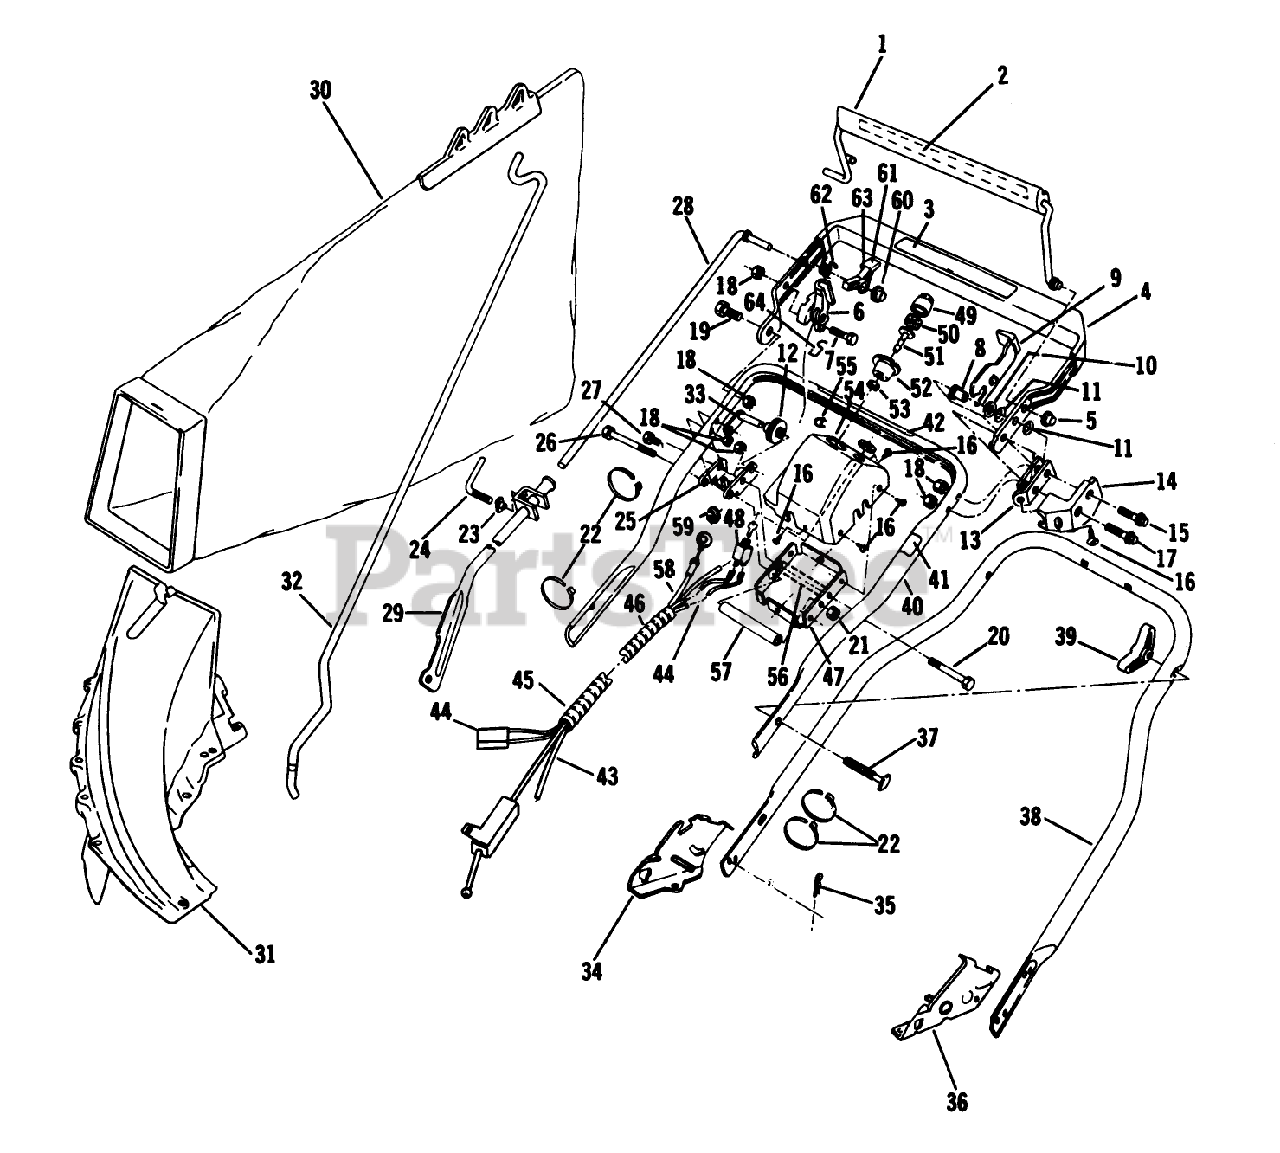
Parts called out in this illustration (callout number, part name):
8	SPACER
10	WASHER M
13	DOWN STOP
14	LOCKOUT GUARD
15	BOLT SHOU
16	SCREW F
17	SCREW
18	LOCKNUT E
19	BOLT
26	BOLT-CONSOLE
30	89802 LB WHOLE GOODS
32	ROD GRASSBAG
34	BRACKET ASM - HANDLE, SP, RH
35	HAIR PIN
36	BRACKET ASM - HANDLE, SP, LH
37	BOLT QUALITY
39	NUT-WING
48	SWITCH AY
50	FILTER S
53	LOCKNUT S
56	SPACER
58	CONTROL CABLE
59	RET. RING
